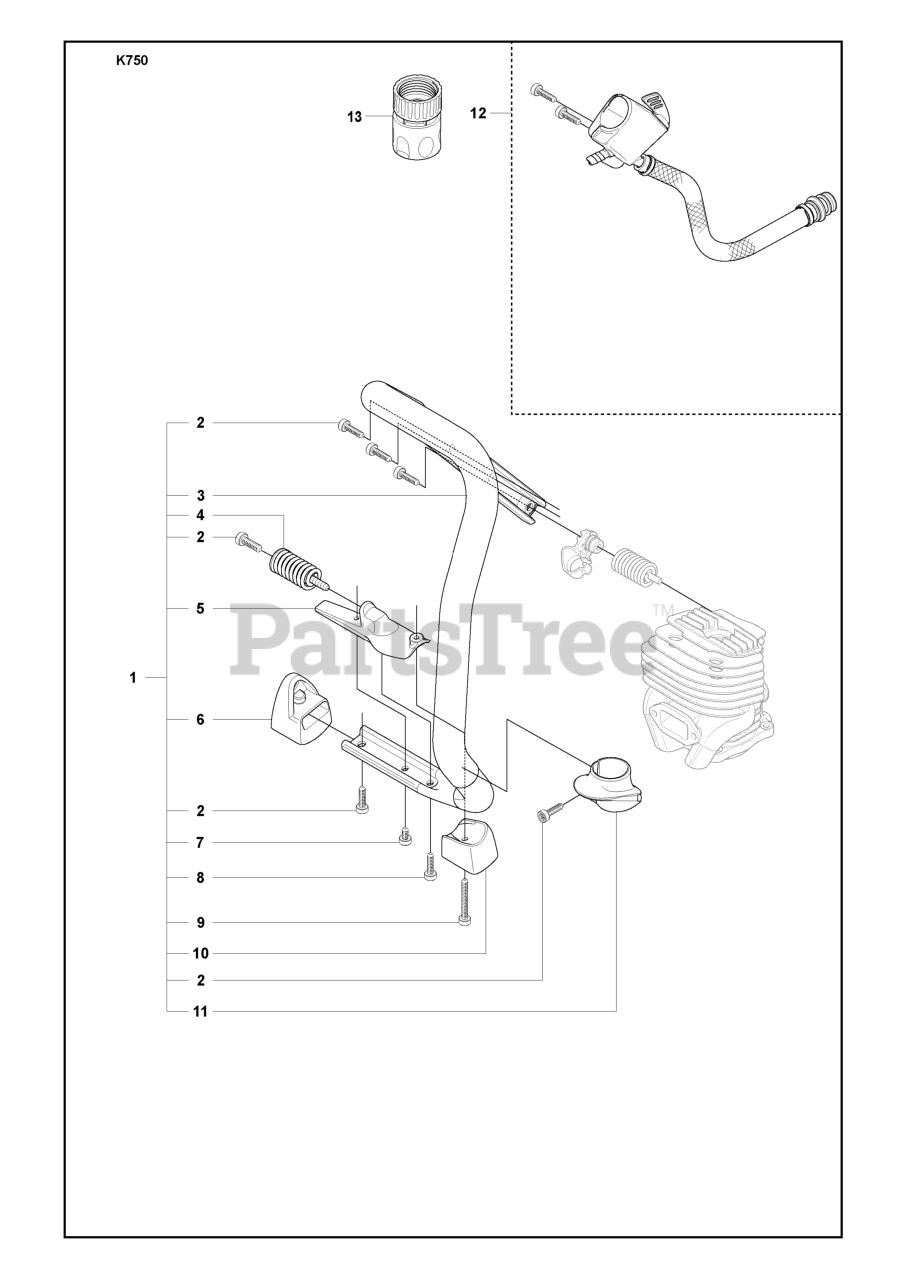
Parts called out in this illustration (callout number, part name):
1	%HANDLE
3	FRONT HANDLE
4	ANTIVIBRATION ELEMENT
5	%SPRING RETAINER
6	GROUND SUPPORT
10	GROUND SUPPORT
12	RP HOSE
13	FEMALE QUICK COUPLER
13	COUPLER, 1/2" HOSE W/STOP ORIG
